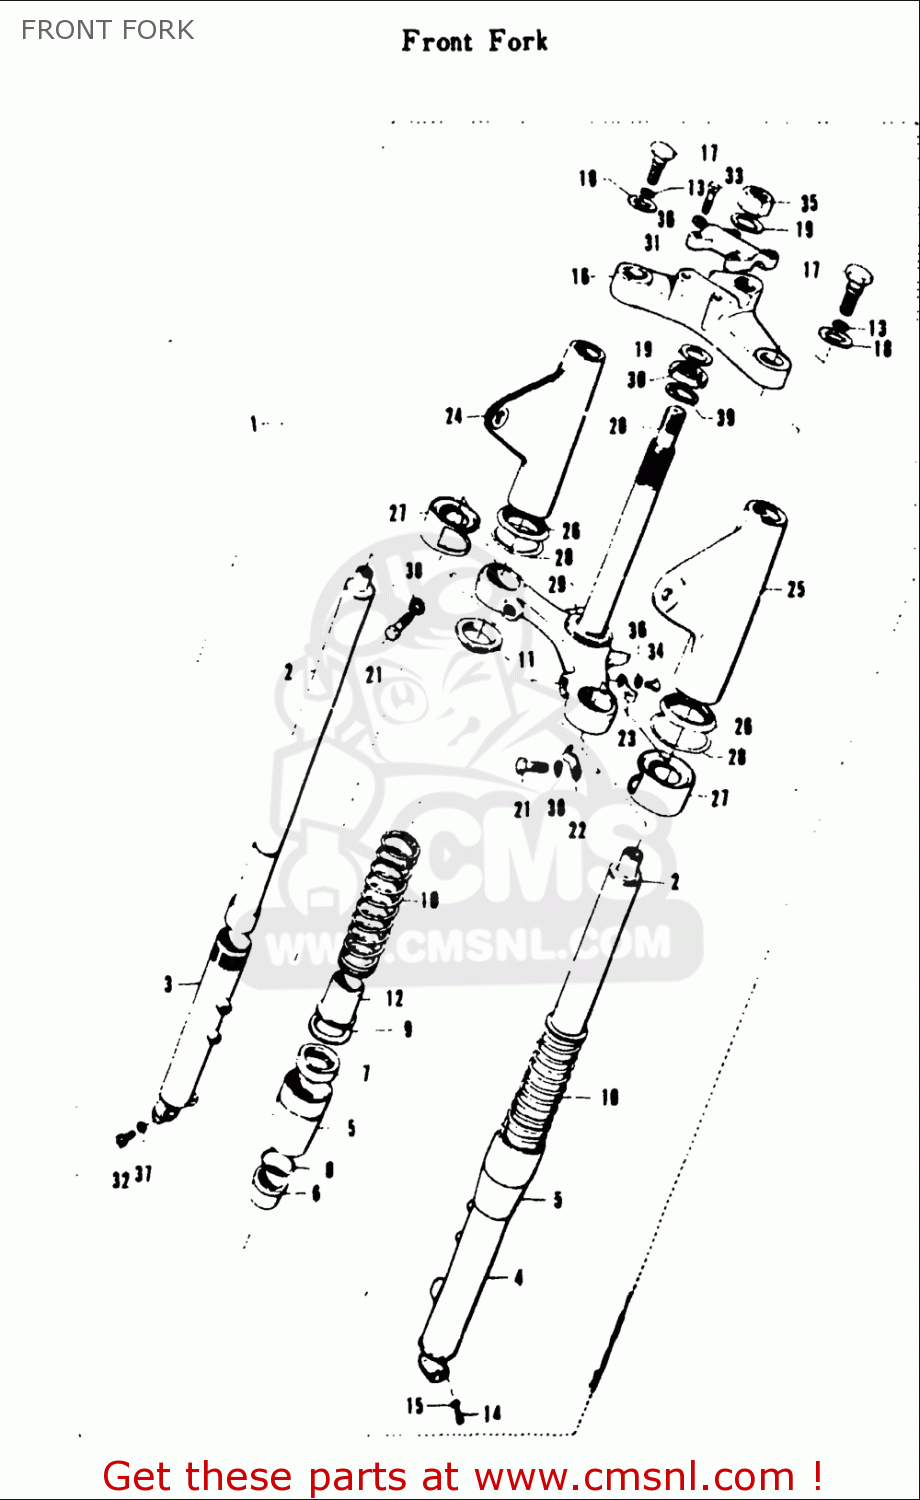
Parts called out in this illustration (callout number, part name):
7	SEAL,OIL
9	WASHER
14	OIL DRAIN PLUG
15	GASKET,DRAIN,PLUG (NAS)
17	CAP,FORK INNER TUBE
18	WASHER
22	CLIP,SPEEDOMETER CABLE
23	CLIP,BRAKE CABLE
26	SEAT,HEADLAMP BRACKET
33	BOLT
35	NUT
36	WASHER,LOCK
37	WASHER,LOCK
38	WASHER,LOCK
39	WASHER
